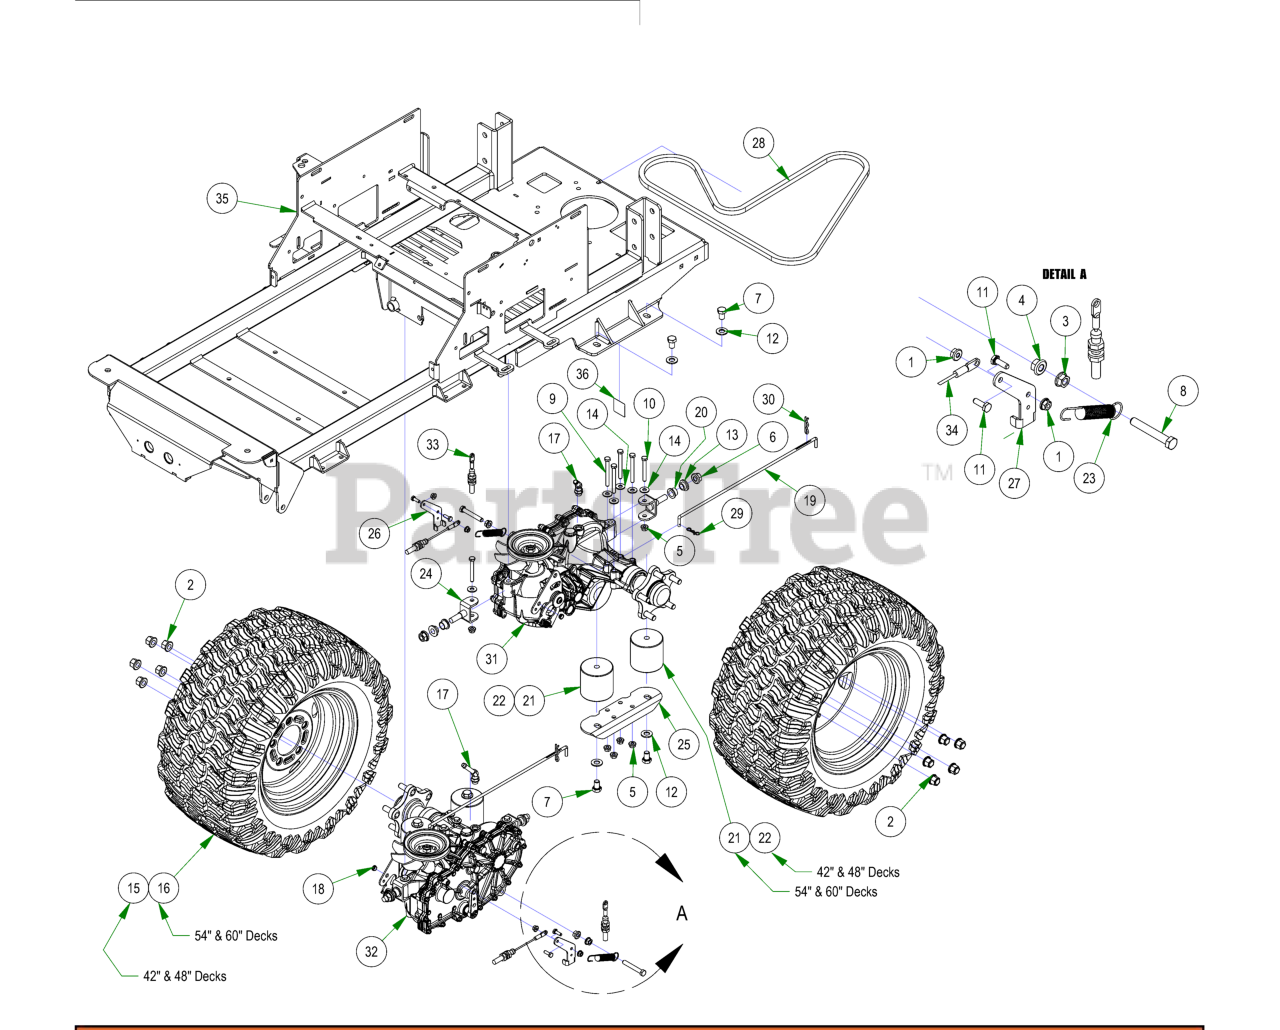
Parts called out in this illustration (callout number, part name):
1	1/4-20 NYL INSERT FLANGE LOCKNUT ZINC
2	Acorn Lug Nut
3	3/8-16 HEX SERRATED FLANGE NUT HARD/ZINC
4	3/8-16 NYLON INSERT FLANGE LOCKNUT (GR.F) ZINC
5	5/16-18 NYLON INSERT FLANGE LOCKNUT ZINC
6	1/2-13 NYLON INSERT FLANGE LOCKNUT ZINC
7	1/2-13 X 3/4 HEX CAP SCREW (GR.5) ZINC
8	3/8-16 X 2-1/2 HEX TAP BOLT (GR.5) ZINC Fully Threaded
9	5/16-18 X 3 HEX CAP SCREW (GR.5) ZINC
10	5/16-18 X 2-1/2 HEX CAP SCREW (GR.5) ZINC
11	1/4-20 X 3/4 HEX CAP SCREW (GR.5) ZINC
12	1/2 SAE FLAT WASHER (1-1/16" OD) GR.8 ZINC YELLOW
13	.525 ID SHOULDER WASHER NYLON
14	5/16 USS FLAT WASHER (7/8 OD) ZINC
15	23x9-12 Reaper Turf Tire & Wheel Assembly
16	23x11-12 Reaper Turf Assembly
17	ZT Fitting, 3/8 x 3/8 45 Degree, 4603-6-6
18	Drive Arm Transaxle Spacer
19	Neutral Rod
20	.627 ID X .753 OD X .500 LGTH X 1.000 FLG OD X .094 FLG THICK FLANGED BEARING OIL-IMPREG BRNZ
21	Vibration Mount-Green Dot
22	Vibration Mount- Red Dot
23	Brake Return Spring
24	Maverick Rear Transaxle Pivot Bracket
25	Rear Suspension Transaxle Mount
26	Brake Arm Ext (Left)
27	Brake Arm Ext (Right)
28	75.8" Pump Belt
30	Neutral Rod Clip
31	Compact Outlaw/Revolt Transaxle Left 3400
32	Compact Outlaw/Revolt Transaxle Right 3400
33	2021 Load Balanced Brake Cable 1
34	2021 Load Balanced Brake Cable 2
35	2023 Maverick Frame - Painted
36	Patent Decal
